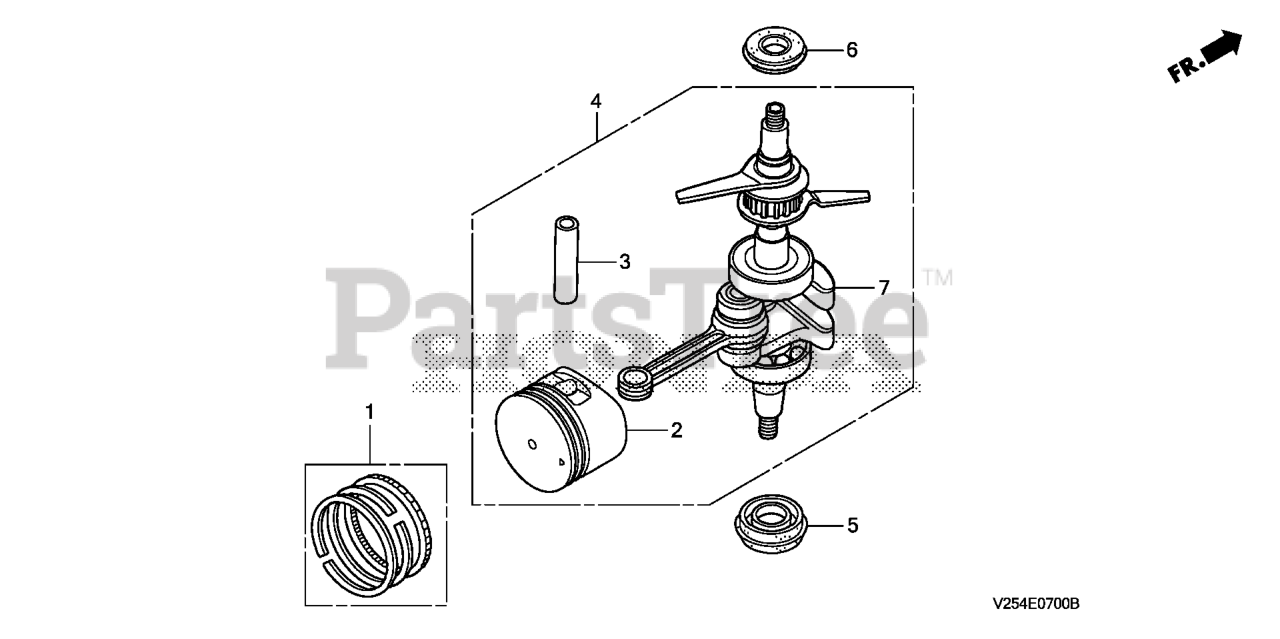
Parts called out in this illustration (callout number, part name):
1	RING SET, PISTON
1	RING SET, PISTON (TPR)
2	PISTON (STD)
3	PIN, PISTON
4	CRANKSHAFT
5	OIL SEAL (12X24X5)
6	OIL SEAL (10X20X5)
7	CRANKSHAFT
